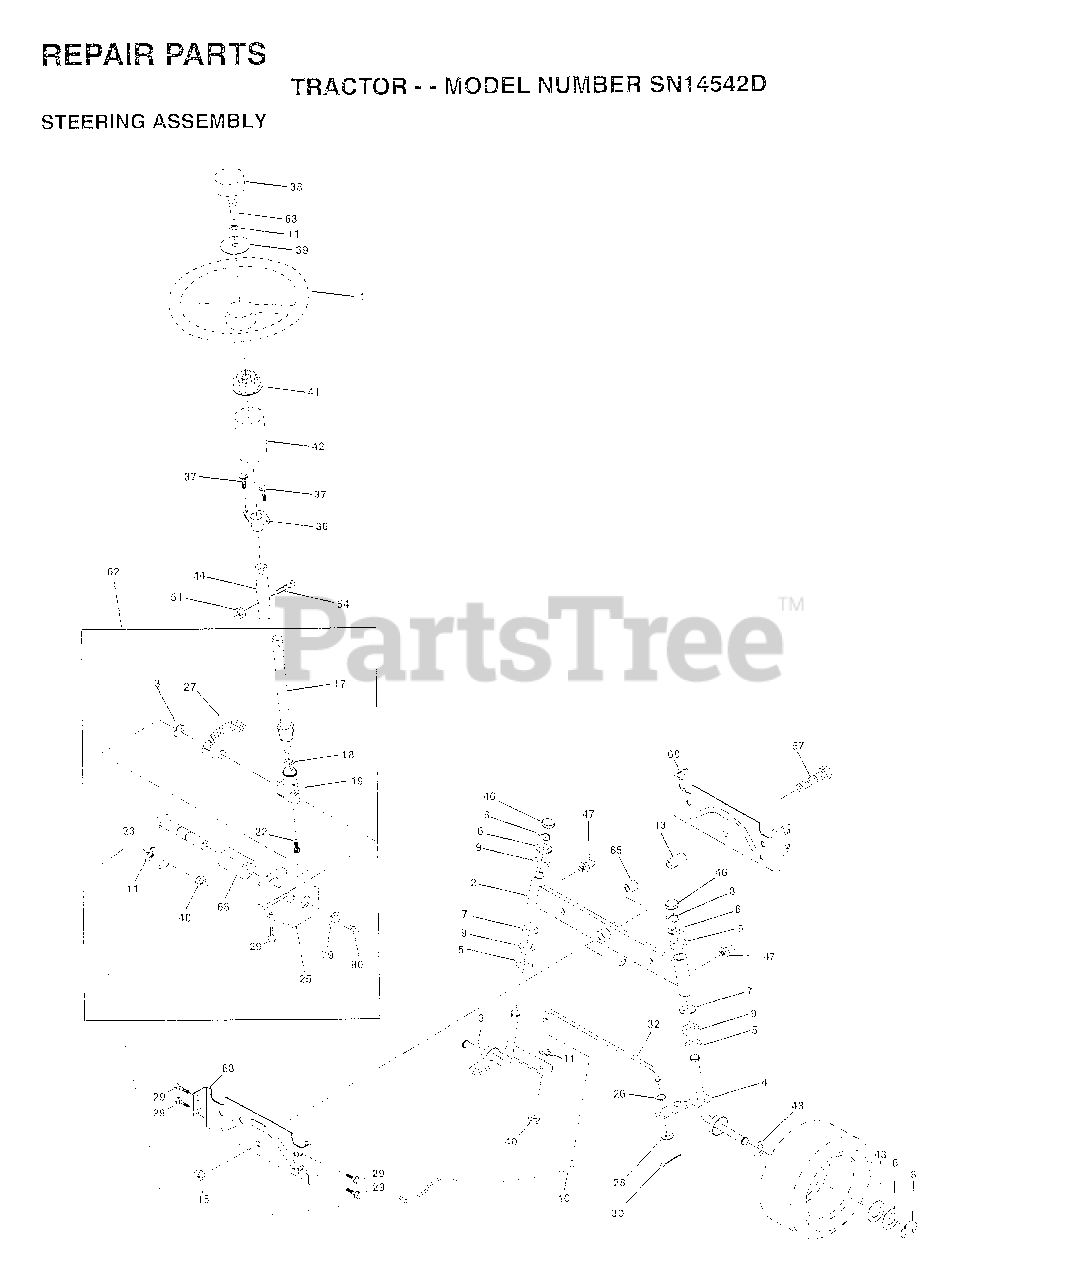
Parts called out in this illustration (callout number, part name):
1	WHEEL STR AYP BLK
2	AXLE ASM
3	SPINDLE.ASM.LH
4	"SPINDLE ASM,RH"
5	WASHER .T
6	WASHER
7	WASHER
8	RING
9	COL. SRTG. BEAR.
10	DRAGLINK-STAMPED
11	LOCKWASHER
13	BEARING AXLE
15	"NUT-LOC,FLANGE LT"
17	SHAFT ASM STEERIN
18	THRUST WASHER
19	SUPPORT.SHAFT.STEER
22	SCREW.HX.WSH.HD
23	SHAFT.ASM.PITMAN
25	BRKT-STEERING
26	BUSHING.DRAGLINK
27	GEAR SECTOR
28	WASHER
29	SCREW
30	COTTER PIN
32	TIE ROD
36	BUSHING.STEERING
37	"SCREW-TT,10-32 FL"
38	CAP STEER AYP
39	WASHER T
40	GRIPCO NUT
41	ADAPTER LT
42	BOOT.STEER.PL
43	WASHER
44	EXT SHAFT STEERIN
46	CAP
47	ZERK M
51	NUT
54	BOLT
62	KIT.STEER.ASM
63	BOLT
65	SPACER AXLE
66	"BEARING-ARM,PITMA"
67	BOLT
68	BRACE AXLE
79	WASHER
80	BOLT.HX.NYLON3/8-16X3/
